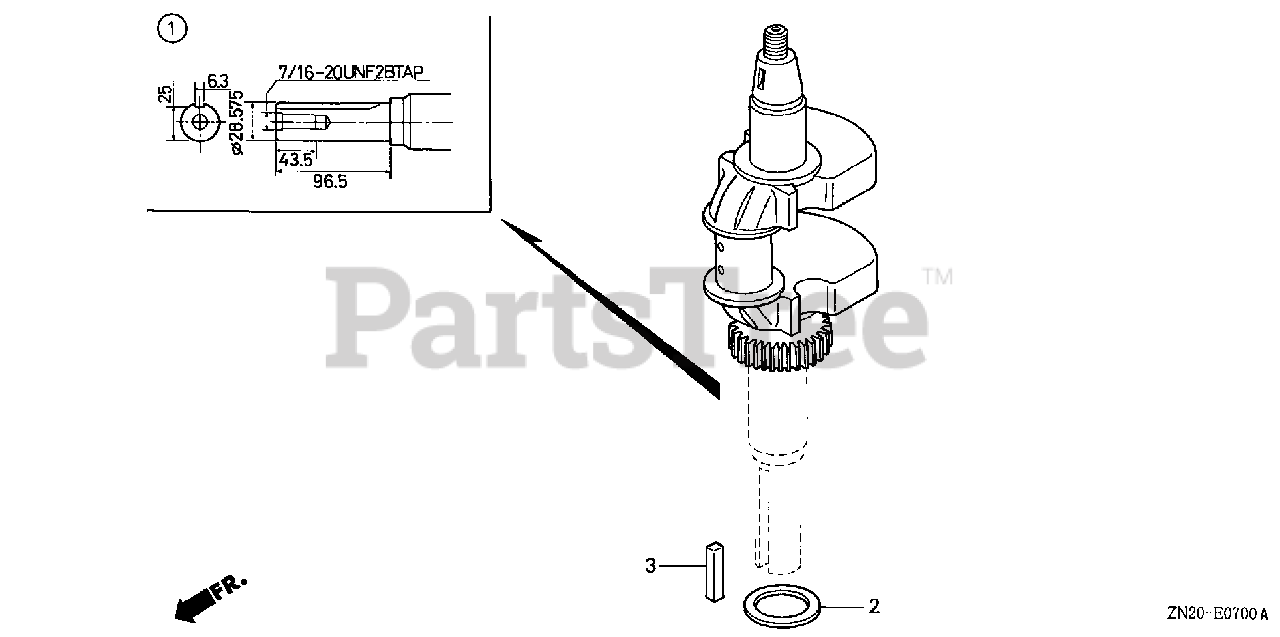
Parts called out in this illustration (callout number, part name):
1	CRANKSHAFT
2	WASHER, CRANKSHAFT THRUST (38.5X54.0X1.0)
3	KEY (6.3X6.3X43)
